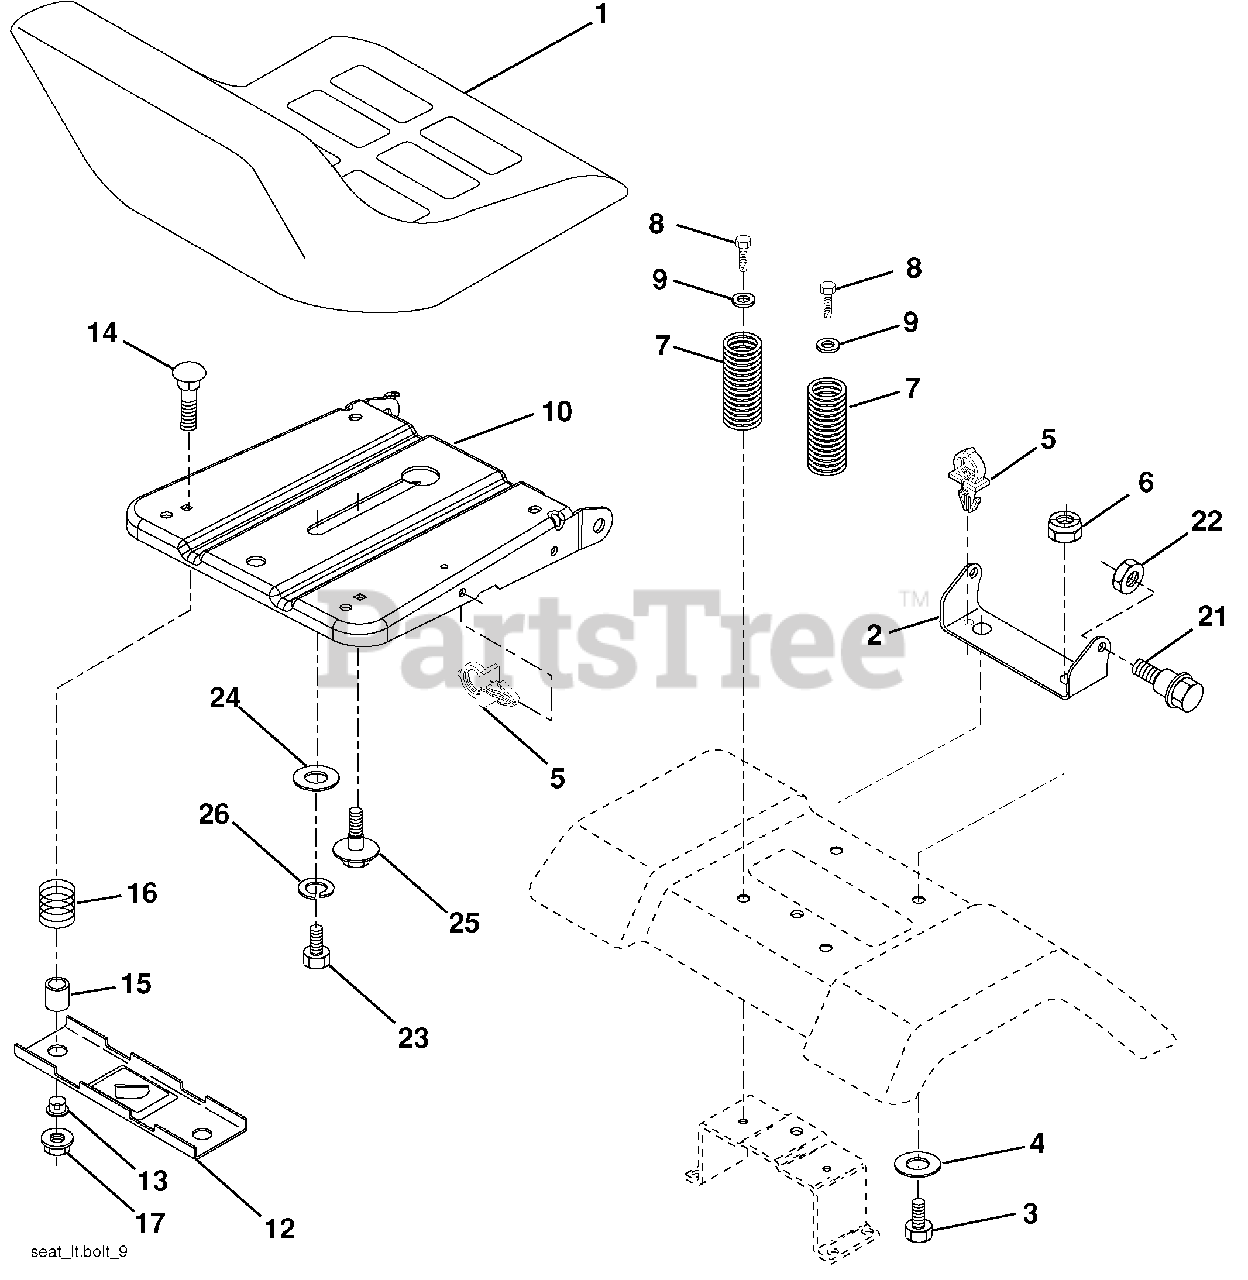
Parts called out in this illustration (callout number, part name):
1	Seat
2	Bracket Seat Pivot
3	Bolt Hex 3/8 - 16 x 1
4	Washer 13/32 x 1 x10 Ga.
5	Clip Push-In Hinged
6	Nut Lock Hex w/Ins 3/8 - 16
7	Spring Seat Cprsn 2 250 Blk Zi
8	Screw 3/8-16 x 1.5
9	Washer 13/32 x 1 x 14 Ga.
10	Pan Pnt Seat
12	Bracket Pnt Mounting Switch
13	Bushing Snap Blk Nyl
14	Bolt Rdhd Sht Nk 1/4 - 20 x 1 -1/2
15	Spacer Split .28 x .96
16	Spring Cprsn
17	Nut Lock 1/4 Lge Flg
21	Bolt Shoulder 5/16-18 unc-2A
22	Nut Lock Hex w/Ins 5/16 - 18
23	Bolt Hex
24	Washer 17/32 x 1-3/16 x 12 Ga.
25	Bolt Shoulder 5/16-18 x .62
26	Washer Lock Hvy Hlcl Spr 1/2
